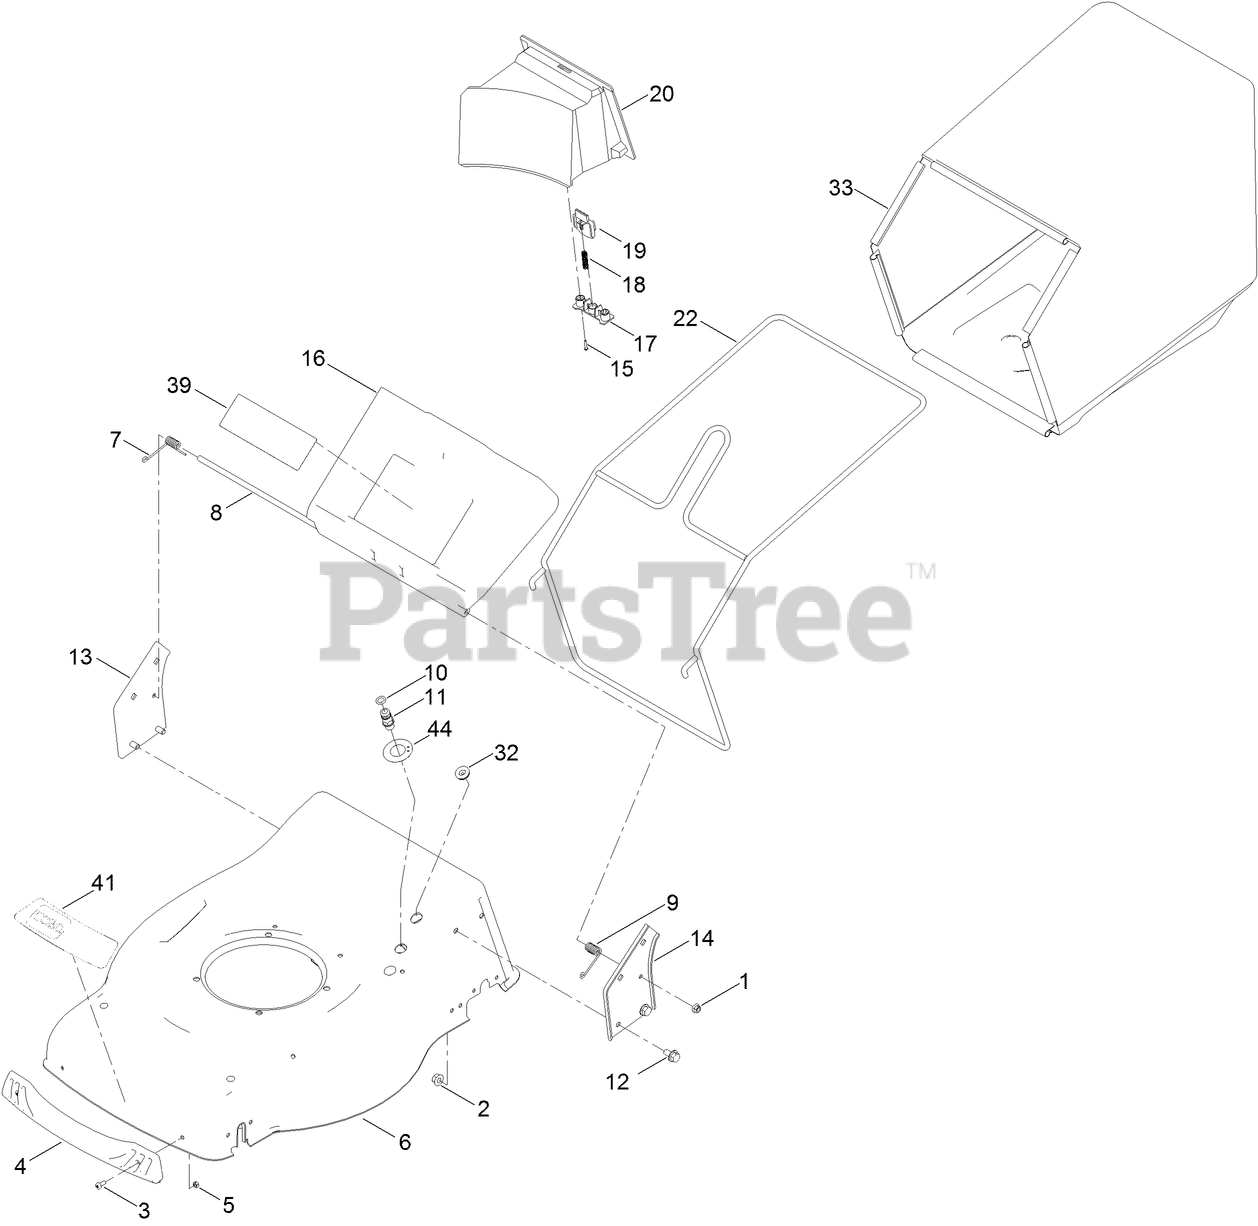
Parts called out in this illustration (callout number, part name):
1	NUT-LOCK, FLANGE
2	NUT-LOCK, FLANGE
3	SCREW-TOOTH
4	BUMPER-FRONT
5	NUT-LOCK
7	SPRING-TWIST, RH
8	ROD-SPRING, REAR DEFLECTOR
9	SPRING-TWIST, LH
10	O-RING
11	PORT-WASH
12	BOLT-HH, FLANGE
13	BRACKET-HANDLE, RH
14	BRACKET-HANDLE, LH
15	SCREW-SELF DRIVING
16	DEFLECTOR-REAR
17	PRESSING BOARD-LOCK BUTTON, MULCH
18	SPRING-BUTTON, MULCH
19	LOCK-BUTTON, MULCH
20	PLUG-MULCH
22	FRAME-BAG, GRASS
32	SHEATH-CABLE, PROTECTIVE
33	BAG-GRASS
39	DECAL-SAFETY
41	DECAL-SHROUD
44	DECAL-PORT, WASHOUT
